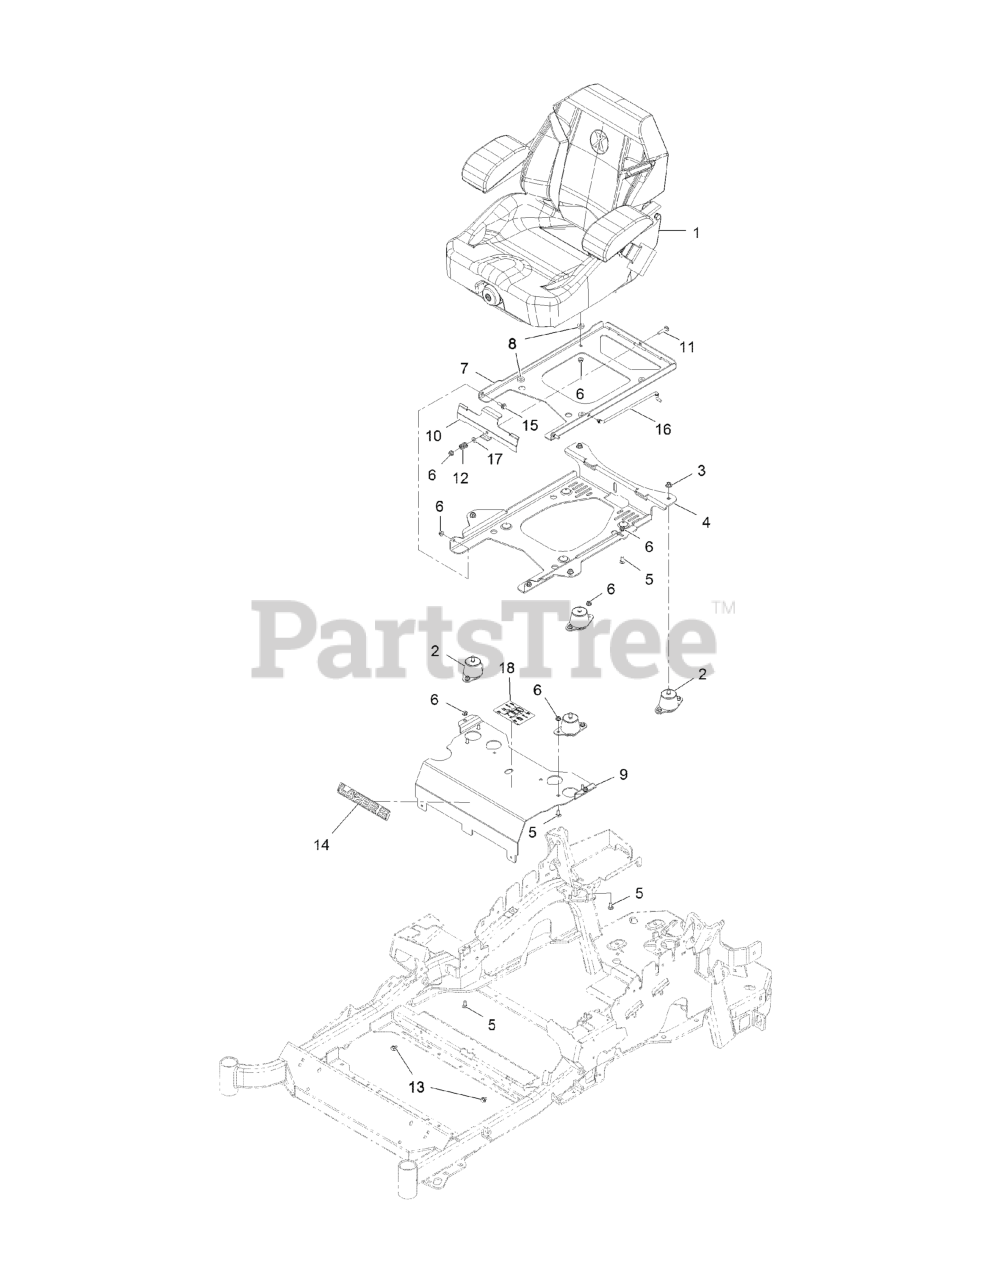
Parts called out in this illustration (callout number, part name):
1	KIT-SUSPENSION SEAT
2	ISOLATOR-SEAT
3	NUT-HF, NI
4	PLATE-TILT, SEAT SUPPORT
5	SCREW-CARR
6	NUT-HF, NI
7	PLATE-FRAME, SEAT
9	Panel-Front, Seat Mount
10	PLATE-LATCH, SEAT
11	BOLT-CARR
12	SPRING-COMPRESSION
14	DECAL, LAZER MODEL
15	SCREW-SHOULDER
16	ROD-PROP
17	WASHER-PLAIN
18	DECAL-SERVICE AID
